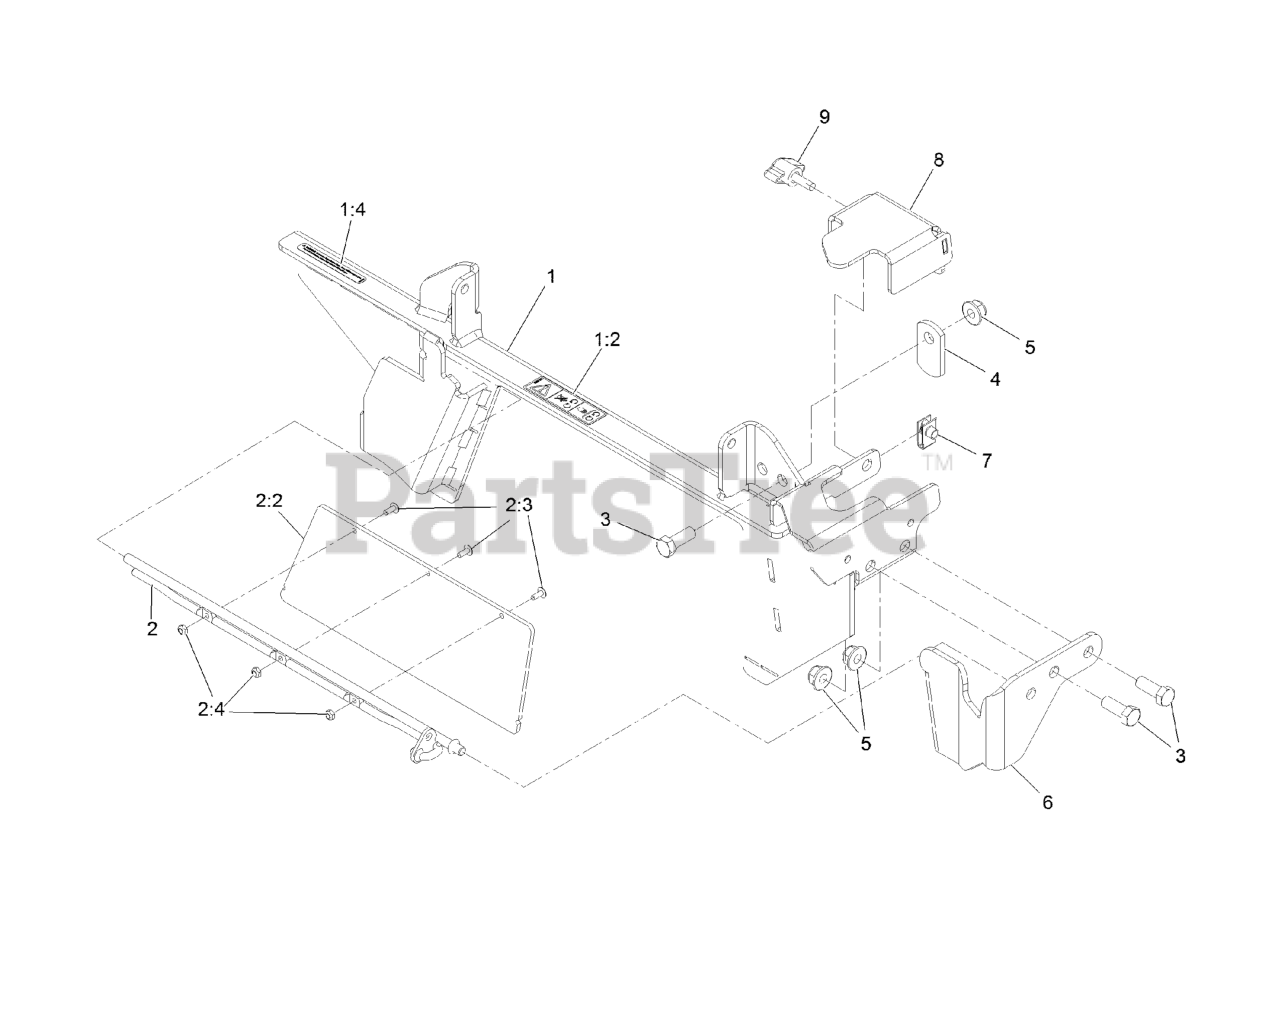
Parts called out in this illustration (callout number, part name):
1	OCD FRAME ASM W/ DECALS
1:2	DECAL, COVER MISSING
1:4	DECAL-WARNING
2	OCD GATE ASM
2:2	GATE-OCD
2:3	SCREW-PTH
2:4	NUT-LOCK, NI
3	SCREW-HH
4	LATCH-CATCHER, GRASS
5	NUT-HF, NI
6	BRKT,CHUTE FRONT
8	BRACKET, CABLE MOUNT
